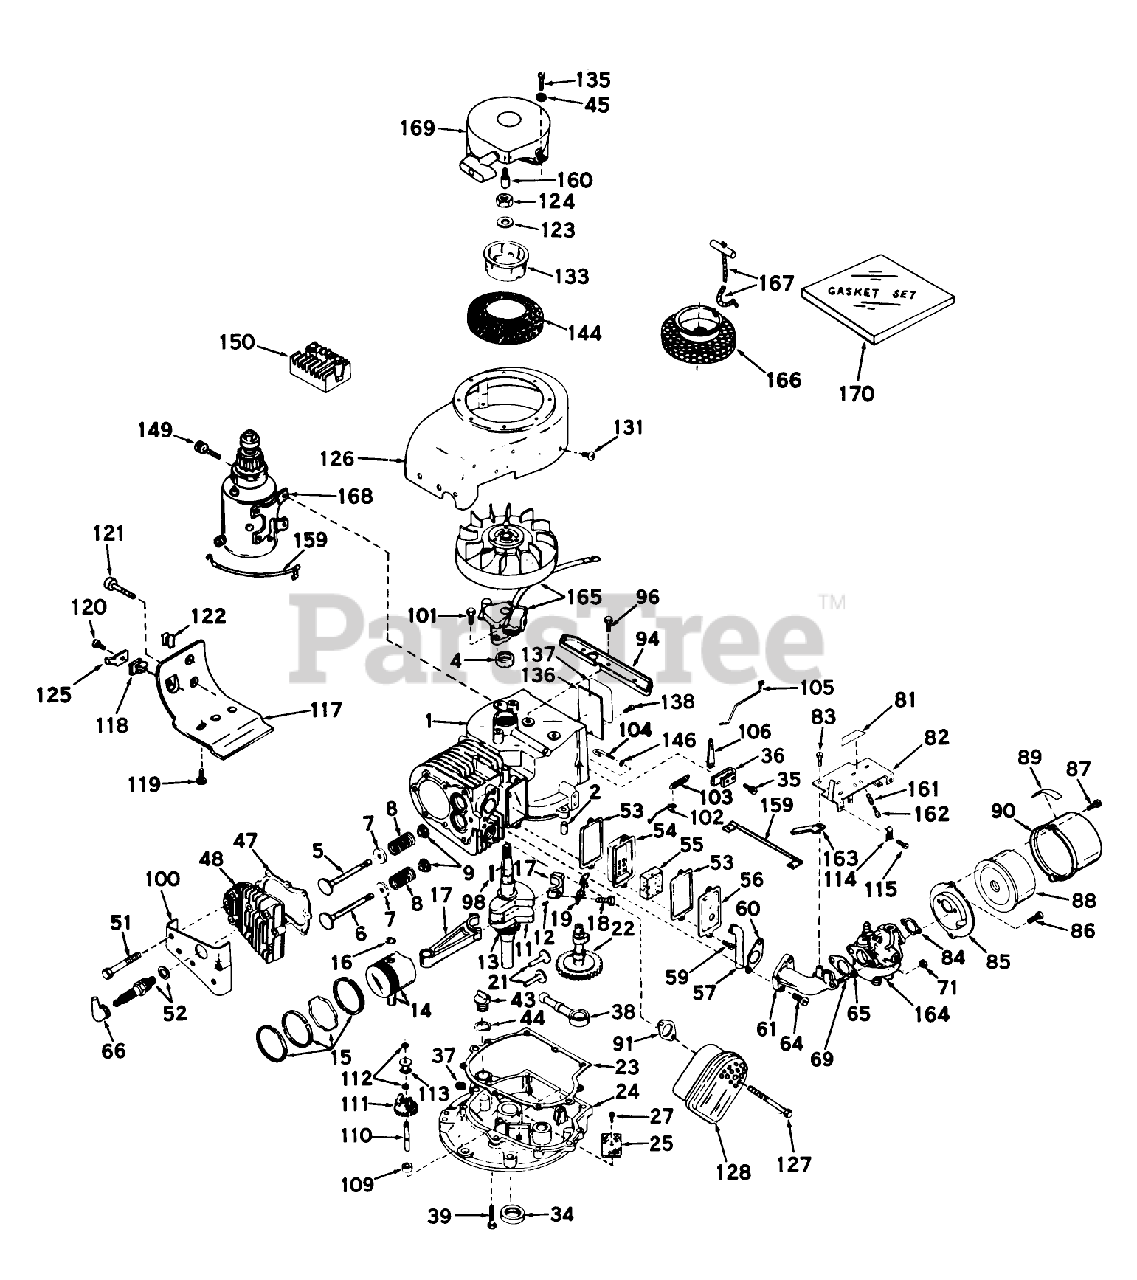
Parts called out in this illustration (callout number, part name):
1	Cylinder Assy. (Incl Nos. 2 4)
2	Pin-Dowel
4	Oil Seal
5	Valve, Intake (Standard)(Incl. No. 9)
5	Valve, Intake (1/32" oversize)(Incl. No. 9)
6	Valve, Exhaust (Standard)(Incl. No. 9)
6	Valve, Exhaust (1/32" oversize)(Incl. No. 9)
7	Cap-Spring, Valve
8	Spring-Valve
9	Keeper-Spring, Valve
11	Crankshaft Assy. (Incl. Nos. 12 13)(Model 935 only)
11	Crankshaft Assy. (Incl. Nos. 12 13)(Model 935E only)
12	Pin, Groove
13	Gear-Crankshaft
14	Piston Pin Assy. (Incl. 2 of No. 16)(Standard)
14	Piston Pin Assy. (Incl. 2 of No. 16)(.010 oversize)
14	Piston Pin Assy. (Incl. 2 of No. 16)(.020 oversize)
15	ORing
15	Ring Set (.010" OS)
15	Ring Set (.020" OS)
17	Rod Assy., Connecting (Incl. Nos. 18 19)
18	Screw, Hex Hd.
19	Plate, Lock
21	Lifter Valve
22	Screw
23	Gasket-Cover, Cylinder
24	Flange Assy., Mounting (Incl. Nos. 25, 27, 34, 37, 43, 44 110)
25	Screen-Oil Filter
27	Screw
34	Seal-Oil
35	Screw
36	Clamp-Lever, Governor
37	Plug-Drain, Oil (SQH 1/4-18)
38	Pump, Oil
39	Screw (1/4-20 x 1-1/4)
43	Plug-Fill, Oil
44	Gasket
45	Washer
47	Gasket-Cylinder Head
48	CYLINDER HEAD
51	Screw
52	SPARK PLUG
53	Gasket-Breather
54	Body-Breather
55	Element-Breather
56	Cover-Valve
57	Tube-Breather
59	Screw
60	Gasket-Intake
61	Pipe-Intake
64	Screw (T-30, 5/16-18x1-3/32)
65	Gasket
66	51005 GIL.ROTARY TI
69	Stud
71	Nut and Lock Washer (1/4-28)
81	Decal
81	Decal, Speed control
82	Control Assy., Speed
83	Screw (10-24 x 9/16)
84	Gasket
85	Bracket
86	Screw (10-32 x 1/2)
87	Screw
88	Element
89	Decal
90	Body
91	Gasket Exhaust
94	Bracket, Blower Housing (Incl. Nos. 131)
96	Screw (1/4-20x19/32)
98	Key-Flywheel
100	Cover, Cylinder head
101	Screw
101	Screw, Hex Hd. Cap, Sems
102	Link Governor Spring
103	Spring Governor
104	Rod, Governor (Incl. Nos. 146)
105	Link Governor
106	Lever-Governor
109	Spacer
110	Shaft, Governor
111	Governor Gear ASM
112	Ring-Retaining
113	Spool-Governor
114	Conduit
115	Screw (10-32 x 3/8)
117	Emnsion, Blower Housing
118	Grommet
119	Screw, Fil. Hd. Sems
120	Screw
121	Screw
122	51004 GIL ROTARY TI
123	Washer
125	Terminal
126	Housing, Blower
127	Screw
128	Muffler
131	Screw, Hex Hd.
133	Cup-Starter
135	Screw
136	IDENTIFICATION PLATE
137	480B GIL SNWTHWR O/
138	Stud
144	Screen, Air
146	Washer-Flat
149	Screw
150	Regulator, Rectifier
159	Wire, Ground
160	Centering
161	Spring-Compression
162	Screw
163	Clip
164	Carburetor
165	Magneto
165	Magneto, Alternator
166	Hub Screen, Rope Starter
167	Rope Assy., Starter
168	Motor, Starter
169	Starter, Rewind
170	Gasket Set
